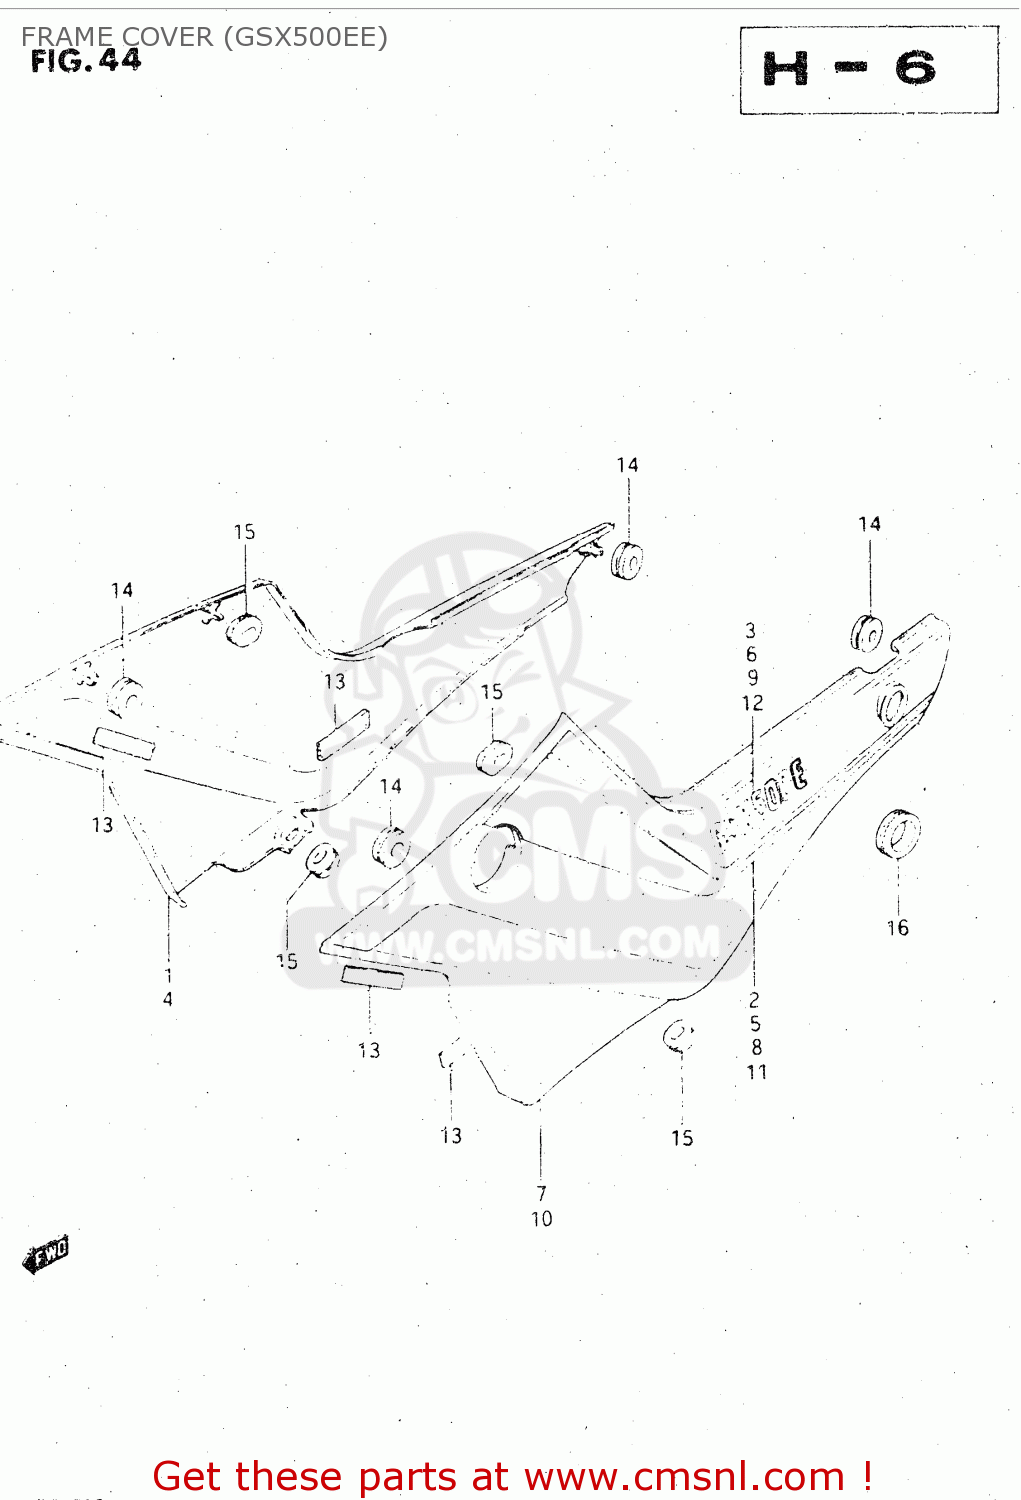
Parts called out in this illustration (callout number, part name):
1	COVER, FRAME RH (BLACK)
2	TAPE SET, FRAME COVER RH
3	EMBLEM
4	COVER, FRAME RH (RED)
5	TAPE SET, FRAME COVER RH
6	EMBLEM
7	COVER, FRAME LH (BLACK)
8	TAPE SET, FRAME COVER LH
9	EMBLEM
10	COVER, FRAME LH (RED)
11	TAPE SET, FRAME COVER LH
12	EMBLEM
13	RUBBER,FRAME COVER
14	CUSHION
15	CUSHION
16	GROMMET,SEAT LOCK HOLE
